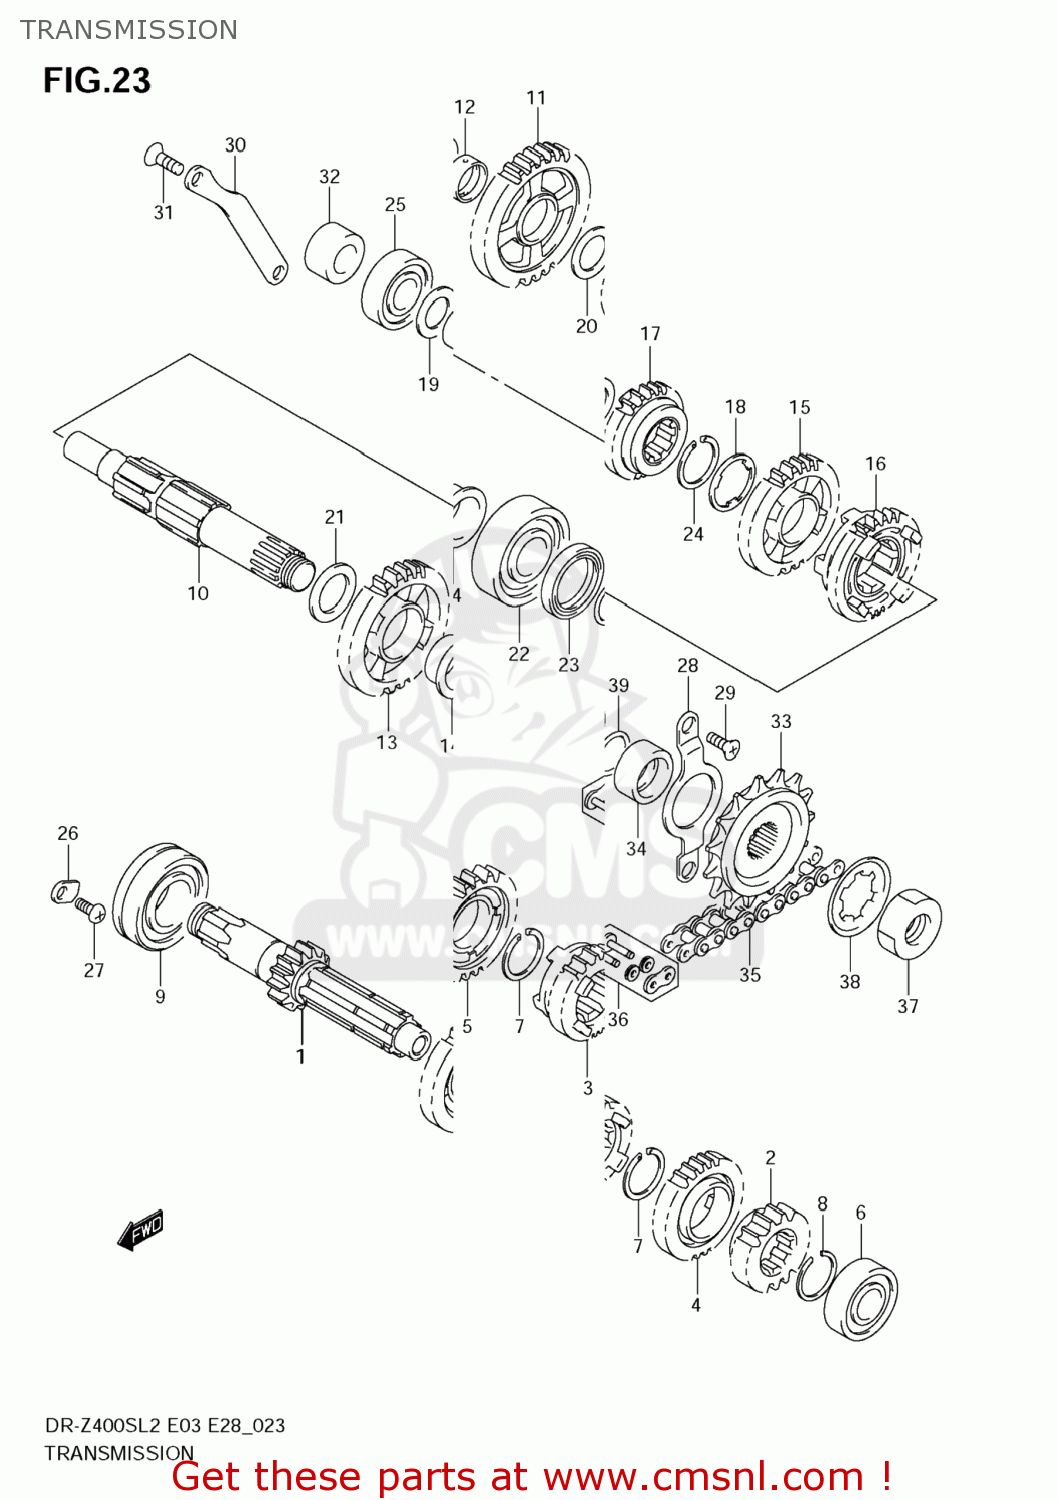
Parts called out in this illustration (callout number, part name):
1	SHAFT,COUNTER(NT:14)
2	GEAR,2ND DRIVE(NT:15)
3	GEAR,3RD DRIVE(NT:16)
4	GEAR,4TH DRIVE(NT:22)
5	GEAR,5TH DRIVE(NT:22)
6	BEARING(17X40X12)
7	CIRCLIP
8	CIRCLIP
9	BEARING(25X52X15)
10	SHAFT,DRIVE
11	GEAR,1ST DRIVEN(NT:32)
12	BUSH,1ST DRIVEN GEAR
13	GEAR,2ND DRIVEN(NT:26)
14	BUSH,2ND DRIVEN GEAR
15	GEAR,3RD DRIVEN(NT:22)
16	GEAR,4TH DRIVEN(NT:24)
17	GEAR,5TH DRIVEN(NT:19)
18	WASHER,LOCK
19	SHIM(17X30X1)
20	SHIM(20X30X1)
21	SHIM(22X34X1)
22	BEARING(22X56X16)
23	SEAL,OIL(30X40X6)
24	CIRCLIP
25	BEARING(17X40X12)
26	RETAINER
27	SCREW(6X12)
28	RETAINER,DRIVE SHAFT OIL SEAL
29	SCREW(6X14)
30	RETAINER,KICK IDLE GEAR
31	SCREW
32	SPACER(17X30.5X16.3)
33	SPROCKET,ENGINE(15T)
34	SPACER,ENGINE SPROCKET
35	CHAIN ASSEMBLY,DRIVE RK520
36	JOINT SET,CHAIN
37	NUT
38	WASHER,LOCK
39	O RING(D:2.5,ID:21)
